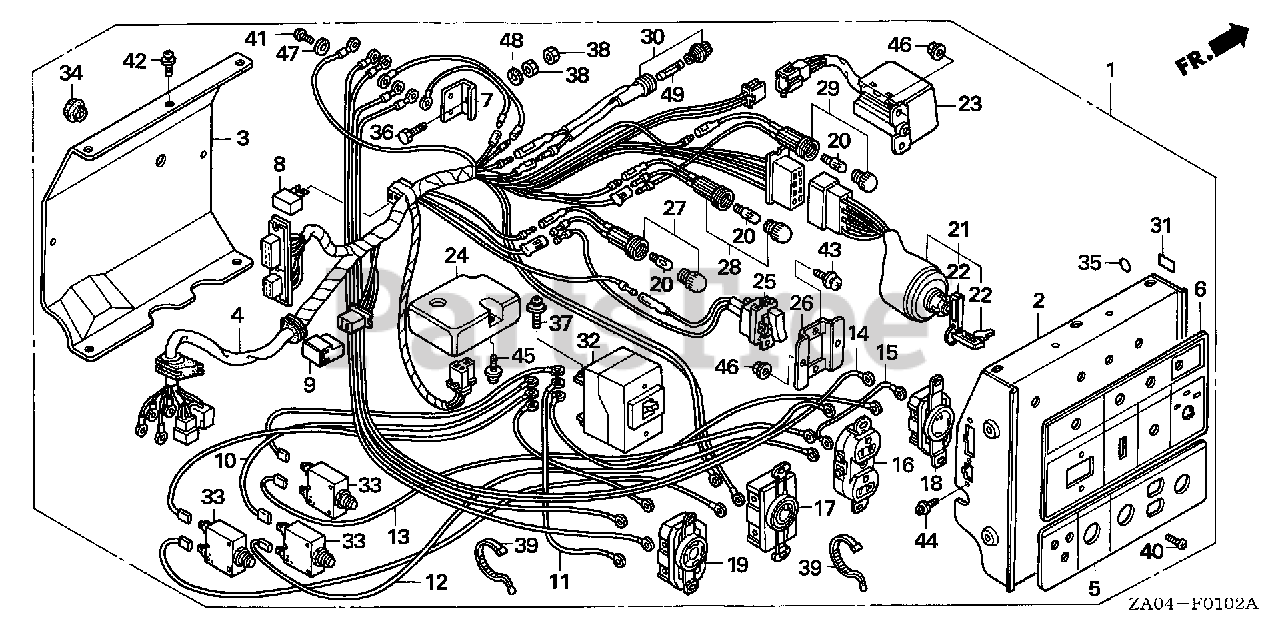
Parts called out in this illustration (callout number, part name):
1	BOX ASSY., CONTROL *NH105* (MAT BLACK)
2	PANEL, FR.
4	WIRE HARNESS
5	MARK, RECEPTACLE PANEL
6	MARK, SWITCH PANEL
7	PLATE, GROUND
8	RECTIFIER ASSY., SILICON (STANLEY)
8	RECTIFIER ASSY., SILICON (SHINDENGEN)
9	STACK ASSY., DIODE (2.7A)
10	SUB-WIRE (A)
11	SUB-WIRE (B)
12	SUB-WIRE (C)
13	SUB-WIRE (D)
14	SUB-WIRE (E)
15	SUB-WIRE (F)
16	RECEPTACLE (20A/125V) (EAGLE / RONG FENG)
17	RECEPTACLE (20A/125V) (NOT AVAILABLE)
18	RECEPTACLE (3-PRONG) (30A/125V)
19	RECEPTACLE (30A/125-250V)
20	BULB, DASH (28V-3W)
21	SWITCH ASSY., COMBINATION
22	KEY
23	RELAY, ALERT
24	CONTROL UNIT, IDLE
25	SWITCH ASSY., IDLE CONTROL
26	STAY, SWITCH
27	SOCKET ASSY., PILOT LAMP
28	SOCKET ASSY., LAMP
29	SOCKET ASSY., LAMP
30	HOLDER, FUSE
31	MARK, FUSE CAPACITY
32	BREAKER, CIRCUIT (25A)
33	PROTECTOR, CIRCUIT (20A)
34	GROMMET, TOP COVER
35	MARK, GROUND
36	BOLT, HEX. (8MM)
37	SCREW-WASHER (6X12)
38	NUT, HEX. (8MM)
39	TIE, CABLE (NATURAL 154X3.4)
40	SCREW, PAN (4X6)
41	SCREW, PAN (6X12)
42	SCREW-WASHER (4X8)
43	SCREW-WASHER (3X6)
44	SCREW-WASHER (4X10)
45	SCREW-WASHER (5X10)
46	NUT, FLANGE (4MM)
47	WASHER, SPRING (6MM)
48	WASHER, SPRING (8MM)
49	FUSE B (15A)
